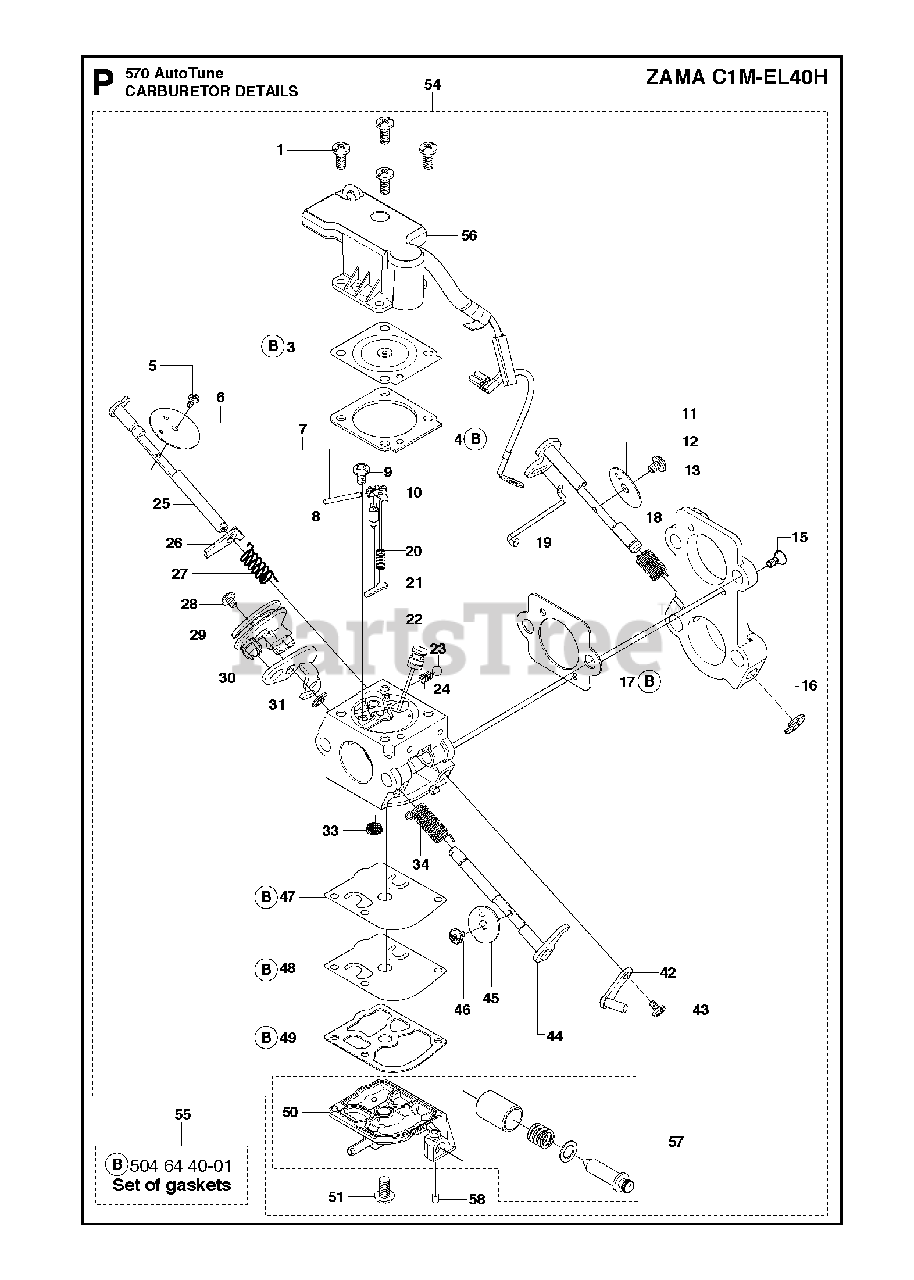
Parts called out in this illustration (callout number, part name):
1	Screw
3	DIAPHRAGM
4	GASKET METERING
5	SCREW
6	CHOKE VALVE
7	PIN FULCRUM
8	INLET NEEDLE
9	SCREW
10	LEVER
11	SHAFT
12	THROTTLE FLAP
13	SCREW
15	SCREW
16	CLIP
17	GASKET
18	SPRING
19	ROD
20	SPRING
21	PLUG
22	JET
23	BALL
24	SPRING
25	CHOKE SHAFT
26	LEVER
27	SPRING
28	SCREW
29	THROTTLE LEVER ASSY
30	LEVER
31	CLIP
33	STRAINER
34	SPRING
42	LEVER
43	SCREW
44	THROTTLE SHAFT
45	FLAP
46	SCREW
47	PUMP DIAPHRAGM
48	DIAPHRAGM
49	GASKET
50	COVER
51	SCREW
54	CARBURETTOR C1M-EL40H
55	GASKET SET KIT
56	VALVE HOUSING ASSY
57	IDLE SPEED SCREW TAMPERPROOF K
58	PLUG
